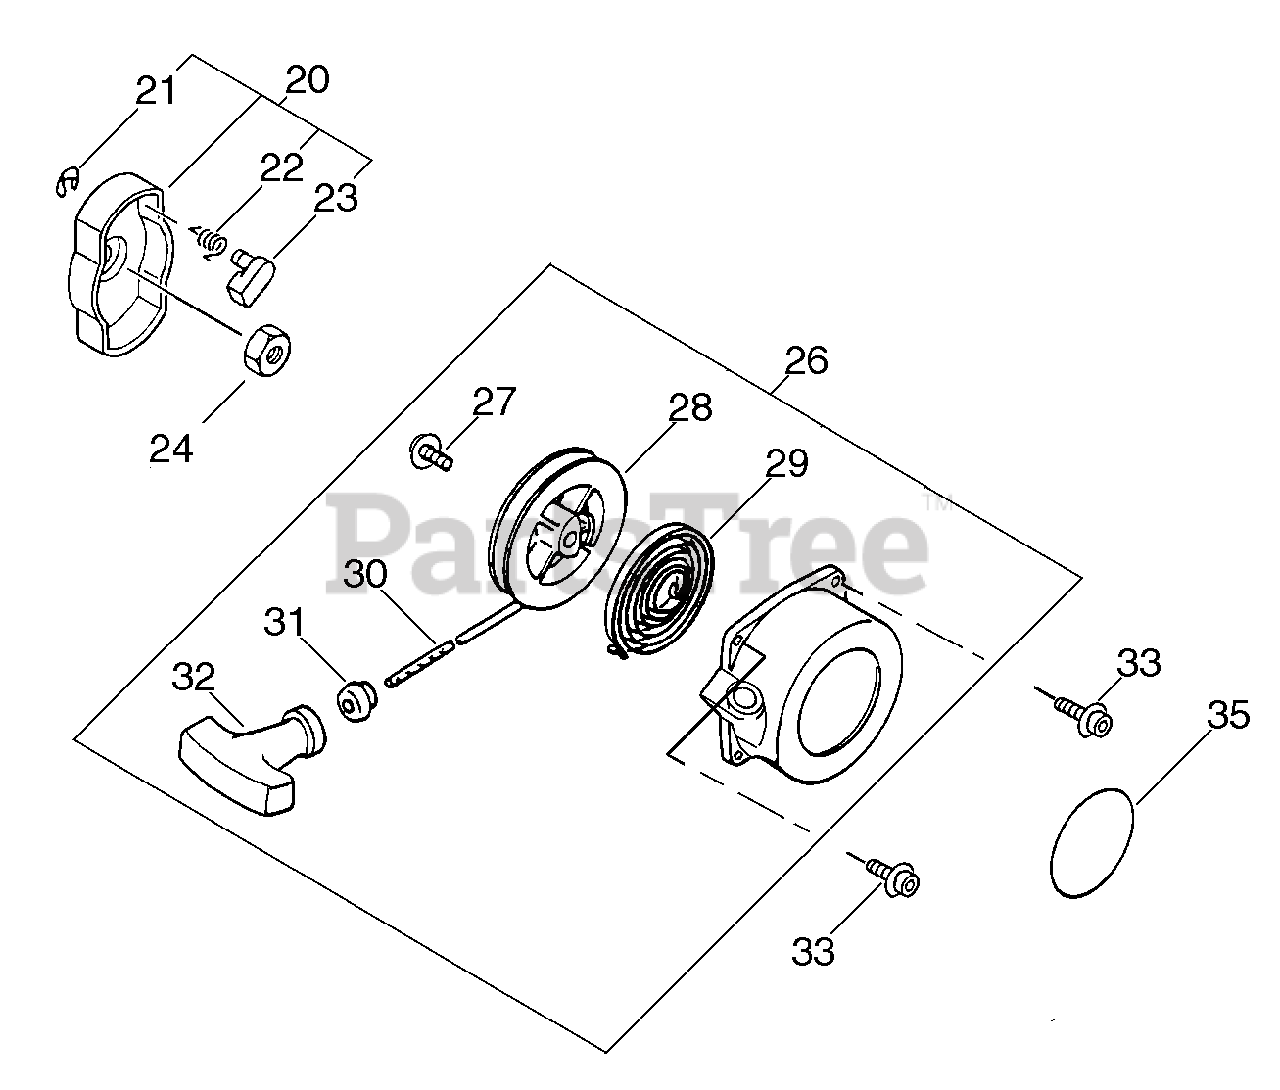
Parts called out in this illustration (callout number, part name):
20	STARTER PAWL ASSY
21	RING, RETAINING - 4
22	SPRING, RETURN
23	PAWL, STARTER
26	STARTER ASSY
28	REEL, ROPE
29	SPRING, REWIND
30	ROPE, STARTER 3.8×1150
31	GUIDE, ROPE
32	GRIP, STARTER
33	SCREW - 5X20
35	LABEL - ECHO
